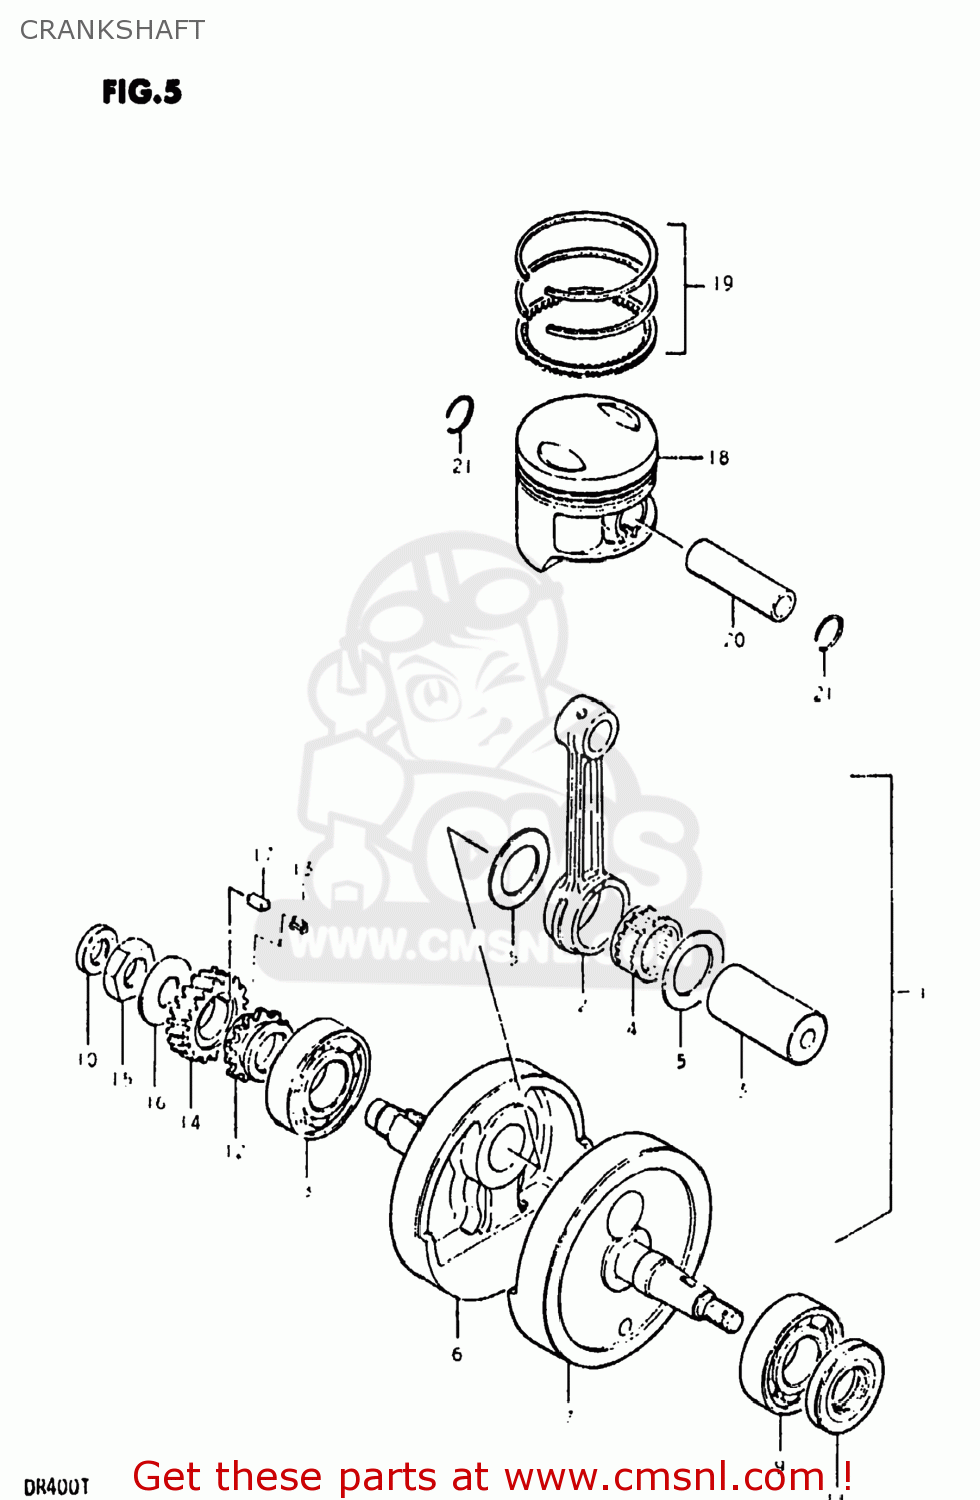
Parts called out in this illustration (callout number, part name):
1	CRANKSHAFT ASSEMBLY
2	ROD,CONNECTING
3	PIN,CRANK
4	BEARING
5	WASHER(34X52X1)
6	CRANKSHAFT
7	CRANKSHAFT,LEFT
8	BALL BEARING 30X72X19
9	BALL BEARING 30X72X19
10	SEAL,OIL(16X30X6)
11	SEAL,OIL(30X58X7)
12	SPROCKET,CAM CHAIN DRIVE
13	KEY,SPROCKET
14	GEAR,PRIMARY DRIVE
15	NUT (20MM)
16	WASHER
17	KEY
18	PISTON
19	RING SET,PISTON
20	PIN,PISTON
21	CIRCLIP
